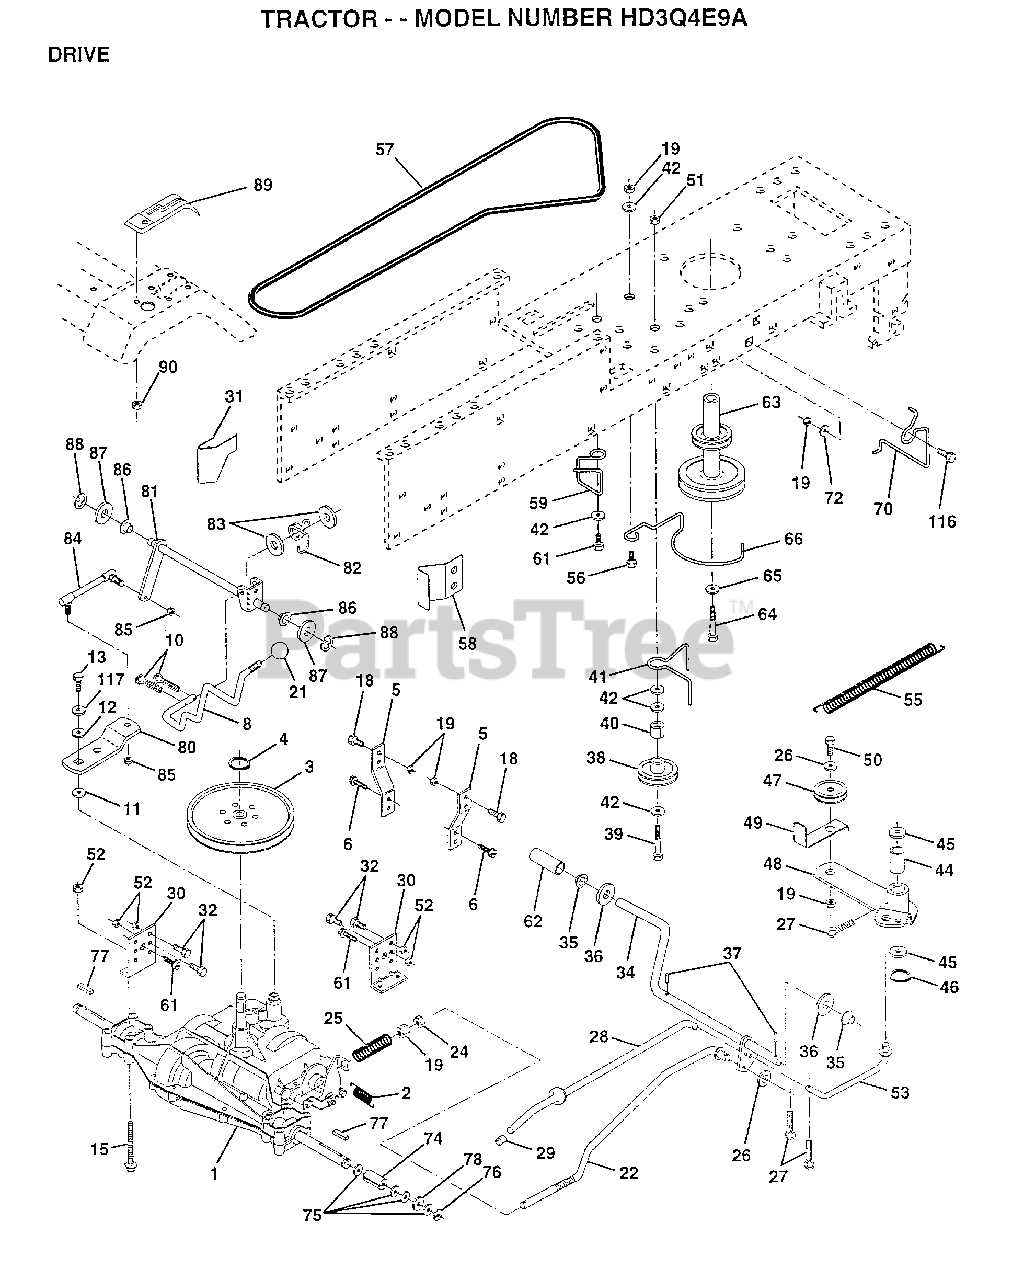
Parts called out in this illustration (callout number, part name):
2	SPRING.BRAKE.RETU
3	PULLEY TRANS
5	STRAP TORQUE
6	SCREW
8	ROD SHIFT FEND LT
10	PIN COTTER 1/8
11	WASH-SHFT PLT LT
12	WASHER
13	BOLT.1/4-28.W/PAT
14	LOCKWASHER
15	BOLT.HX.FLG.5/16
18	BOLT
19	NUT
21	KNOB T (1/2-HOLE)
22	BRAKE ROD
24	NUT
25	SPRING ROD LT
26	WASHER
27	COTTER PIN
28	ROD.BRAKE.PARK.LT
29	PLUNGER CAP T
30	TRANSAXLE MTG BKT
31	"KEEPER,BELT LH T"
32	BOLT
34	SHAFT.PEDAL.FOOT
35	NYLON BEARING
36	WASHER LT
38	PULLEY.IDLER.FLAT
39	BOLT
40	SPACER T
41	BELT KEEPER LT
42	WASHER
44	"LY, BEARING"
45	WASHER LT
46	KLIP RING
48	ARM IDLER
49	RETAIN BELT
53	"LINK, CLUTCH T"
55	"SPRING, RETURN LT"
58	"KEEPER,BELT RH T"
59	KEEPER BELT CNTSP
61	SCREW
62	PEDAL COVER T
63	PULLEY.ENGINE
64	BOLT
65	LOCKWASHER
66	KEEPER.BELT.ENG.L
70	KEEPER BELT ENG
72	WASHER
74	SPACER LT
75	WASHER
76	E-RING LT
77	SQUARE KEY
78	WASHER
80	ARM SHIFT TRANS
81	SHAFT ASM.SHIFT
82	"SPRING,TORSION"
83	WASHER
84	TIE ROD
85	NUT.CNT.LOCK.1/4
86	BUSHING
87	WASHER D
88	KLIP RING
90	NUT
116	BOLT RDHD 3/8-16
